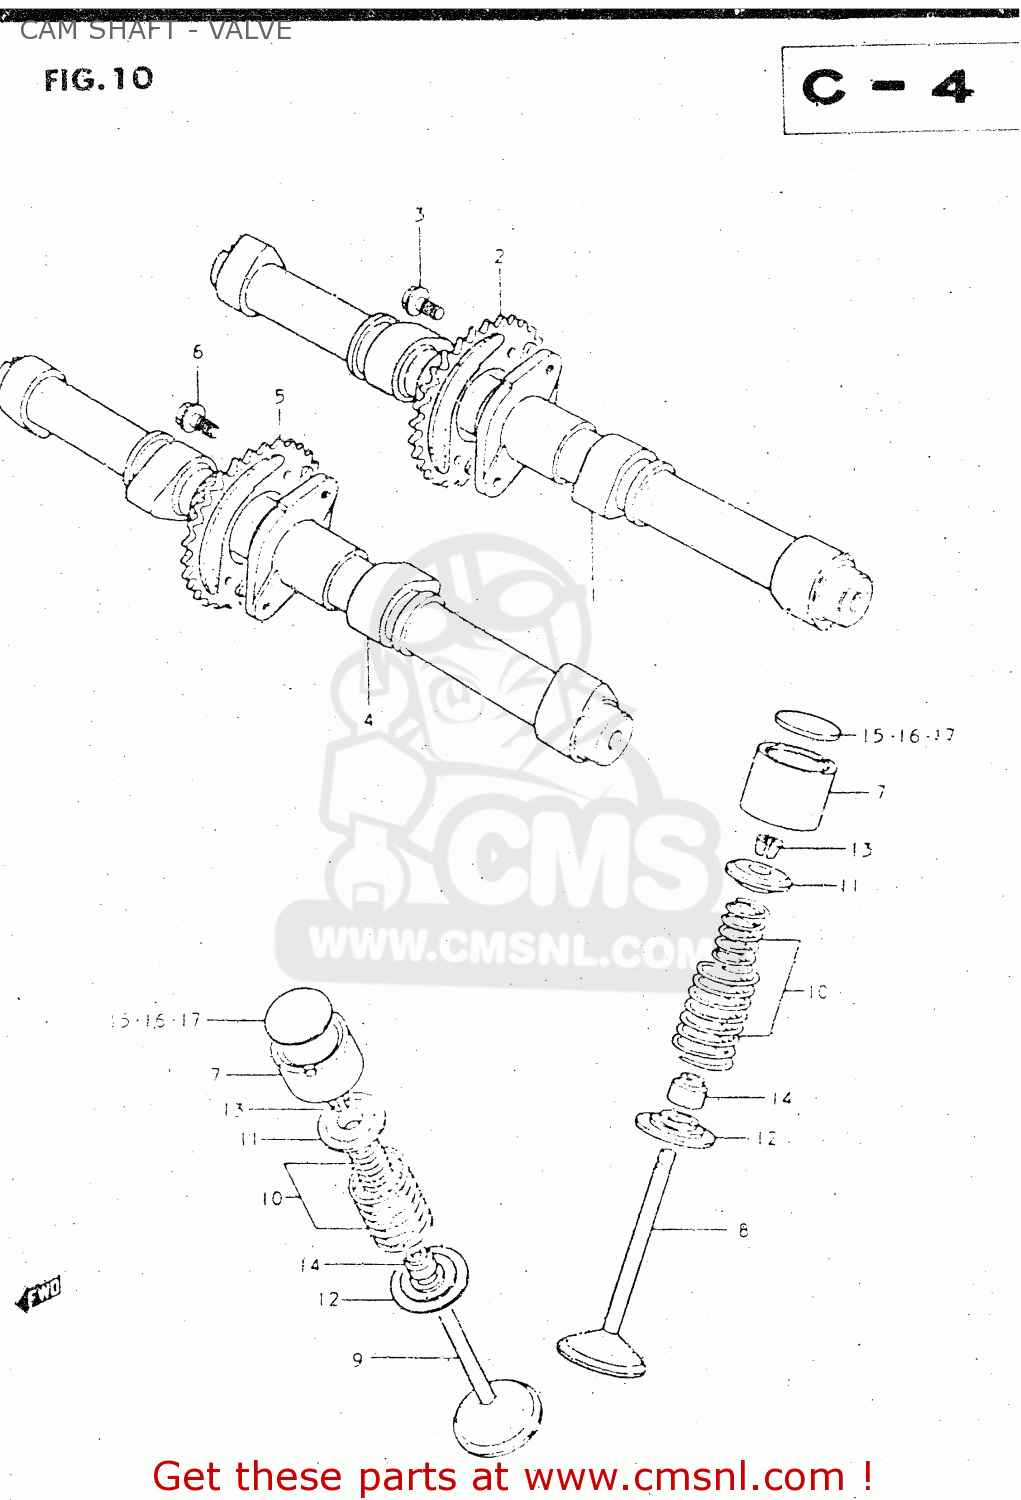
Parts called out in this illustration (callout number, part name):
1	CAMSHAFT,INTAKE
2	SPROCKET,INTAKE CAMSHAFT
3	BOLT(7X11)
4	CAMSHAFT,EXHAUST
5	SPROCKET,EXHAUST CAMSHAFT
6	BOLT(7X11)
7	TAPPET,INTAKE
8	VALVE, INTAKE
9	VALVE, EXHAUST
10	SPRING SET,VALVE
11	RETAINER,VALVE SPRING
12	SEAT,VALVE SPRING
13	COTTER VALVE
14	SEAL,OIL(7X14.4X9)
15	SHIM,TAPPET
16	SHIM,TAPPET
17	SHIM,TAPPET
